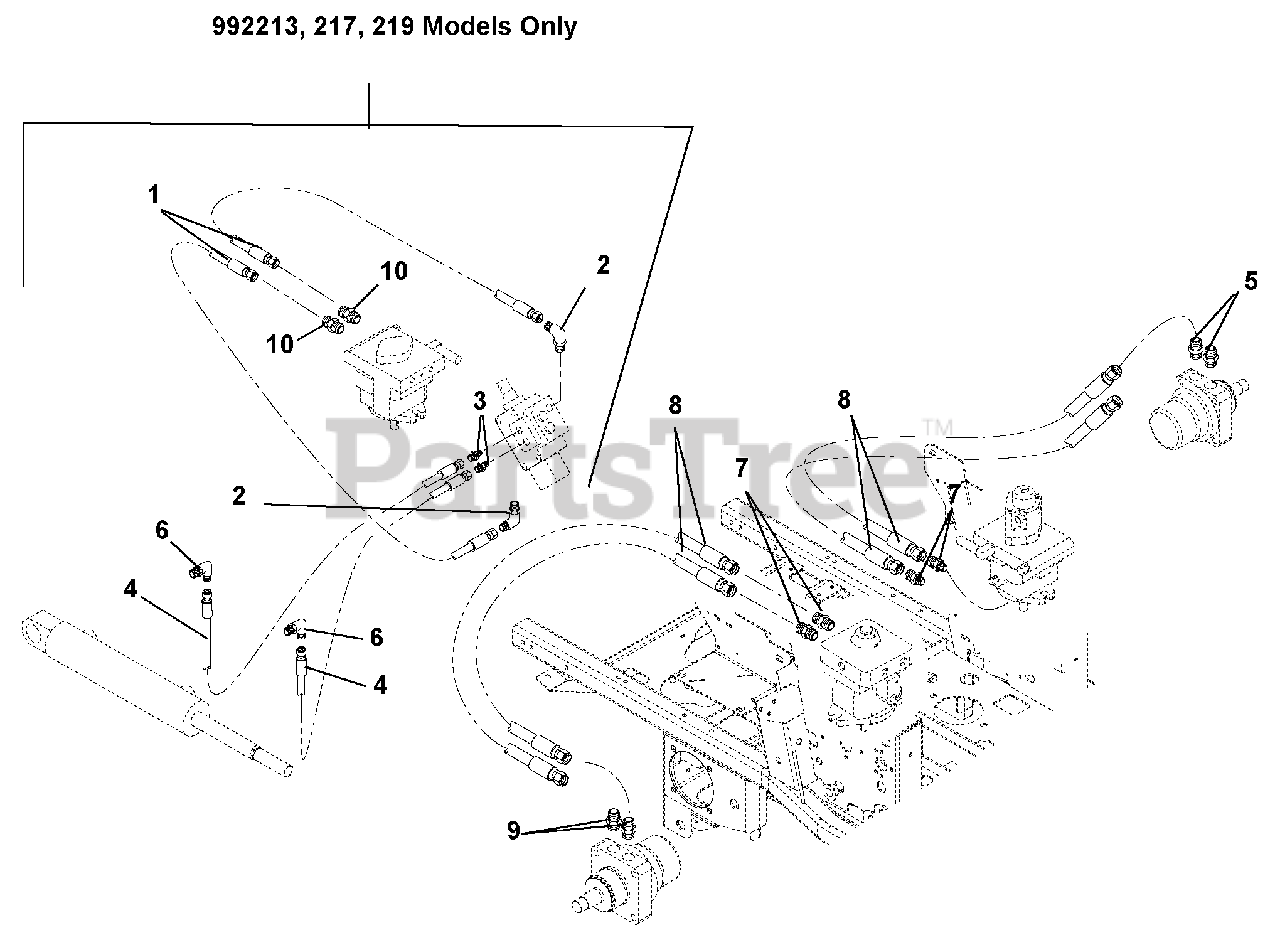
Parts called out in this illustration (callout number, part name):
1	Hose, Hydraulic (992213, 217, 219)
2	Hydraulic, Fitting Elbow (992213, 217, 219)
3	Adapter (4 – 6F5OLO) (992213, 217, 219)
4	Hose, Hydraulic (992213, 217, 219)
5	Fitting, Hydraulic Straight (8 – 10 F5OLO – S)
6	Fitting, Hydraulic (4 C5OLO) (992213, 217, 219)
7	Adapter, Face Seal 8 x 8 .50 O-Ring
8	Hose, Hydraulic .50
9	Adapter, Hydraulic Steel (M10 O – M8F)
10	Fitting, Hydraulic (4 F5OLO) (Supplied with pump) (992213, 217, 219)
